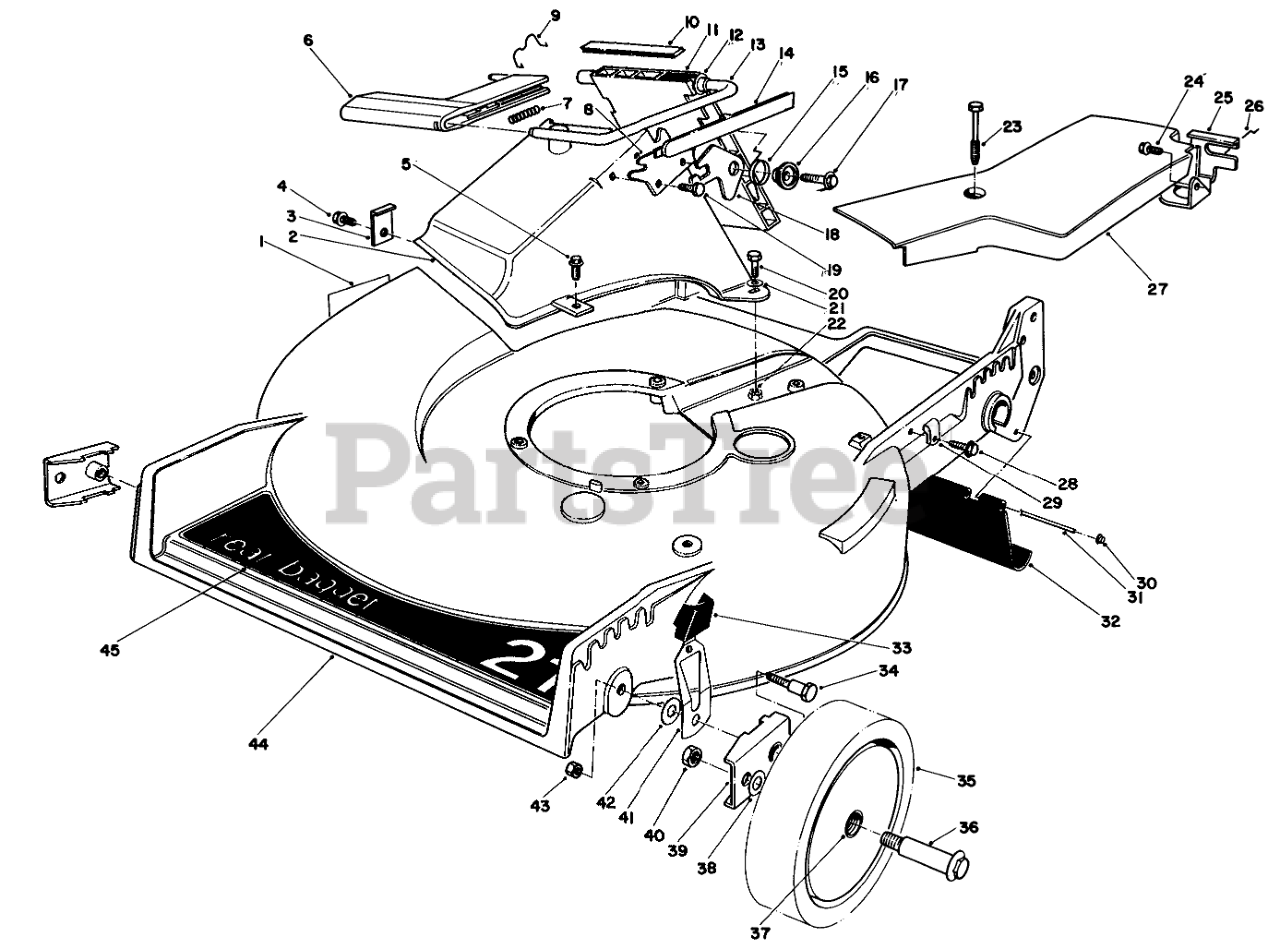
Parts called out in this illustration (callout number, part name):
1	DECAL-DANGER
2	Tunnel Discharge
3	TUNNEL CLIP
4	SCREW
5	Screw
6	Handle-Door
7	Spring
8	DOOR LATCH PLATE
9	DOOR RET SPRING
10	DOOR COVER
11	Door Discharge
12	BUSHING-NYLON
13	DOOR ROD +
14	DOOR HANDLE COVER
15	TORSION SPRING
16	DOOR SPACER
17	SCREW-HWH
18	SAFETY LATCH
19	SCREW-PLASTITE
20	SCREW-HH
21	WASHER-FLAT
22	NUT-LOCK, NI
23	SCREW-HHFTF
24	SCREW-HWHTF
25	Bracket-Traction Adj.
26	RETAINER-CABLE
27	Cover-Belt
28	SCREW
29	CLAMP-CABLE
30	Push Nut
31	Rod-Rear Shield
32	SHIELD-TRAILING
33	KNOB-ARM
34	PIVOT SCREW
35	Wheel & Tire Assembly (Incl. Ref. #37)
36	BOLT-WHEEL
37	BUSHING
38	WASHER
39	HP PIVOT ARM ASM
40	Nut
41	Spring Arm
42	WASHER-PIVOT
43	NUT-LOCK, NI
44	Housing 21" S.P. (Incl. Ref. #1)
45	DECK DECAL
